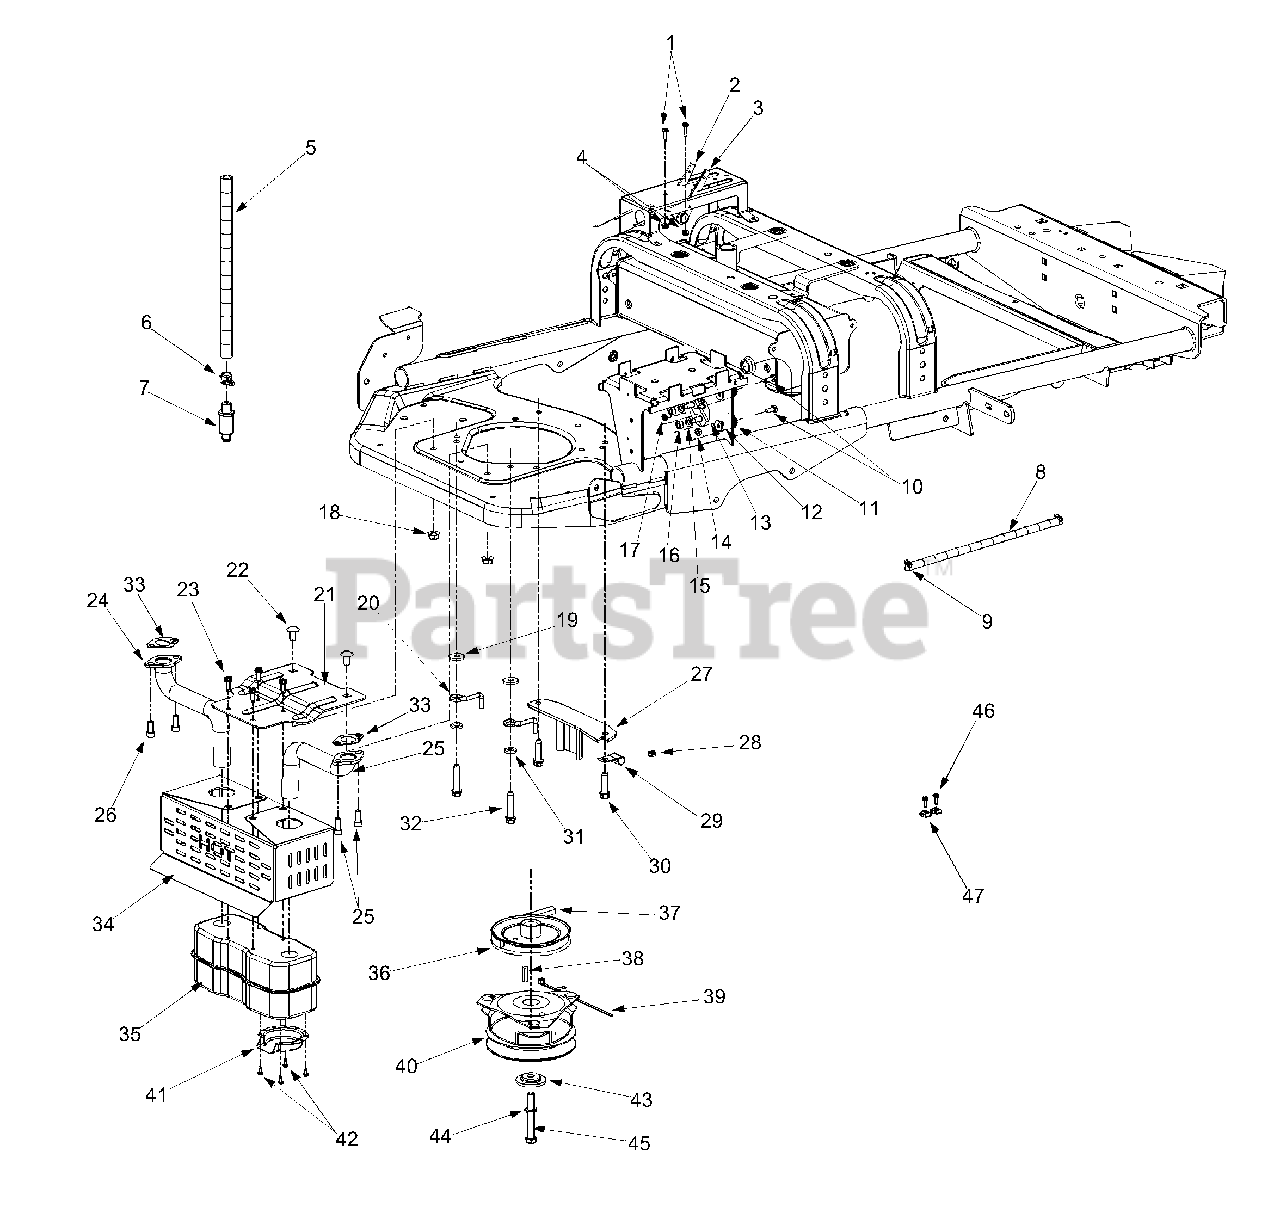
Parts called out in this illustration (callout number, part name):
1	Screw #10-24 x .750
2	Throttle Cable Control 40.5"
3	Choke Cable Control 52.0"
4	Nylon Lock Nut #10-24
5	Oil Drain Hose
6	Oil Drain Cap
7	Oil Drain
8	Fuel Line Hose
10	Hex Cap Screw 1/4-20 x .620
11	Lock Washer 1/4 ID x 3/4 OD
12	Bell Washer .265 ID x .75 OD
13	Solenoid Switch
14	Lock Nut 1/4-20
15	Lock Washer 5/16
16	Hex Nut 5/16 - 18
17	Hex Nut #10-32
18	Flange Lock Nut 3/8-16
19	Flat Washer .385 ID x 1.0 OD
20	Rear Belt Retainer Rod
21	Muffler Bracket
22	Carriage Bolt 3/8-16 x .75
23	Hex Washer Screw 1/4-20 x .750
24	Exhaust Pipe RH
25	Exhaust Pipe LH
26	Screw
29	Heat Shield Cable Clip
30	Hex Washer Screw 3/8-16 x 1.5
32	Hex Washer Screw 3/8-16 x 1.875
33	Gasket
37	V-Belt
40	Electric PTO Clutch
41	Muffler Deflector
42	Hex Washer Screw #8-32 x .375
43	Spacer Clutch
44	Lock Washer 7/16
45	Hex Cap Screw 7/16-20 x 3.25
46	Hex Washer Screw #10-32 x .625
